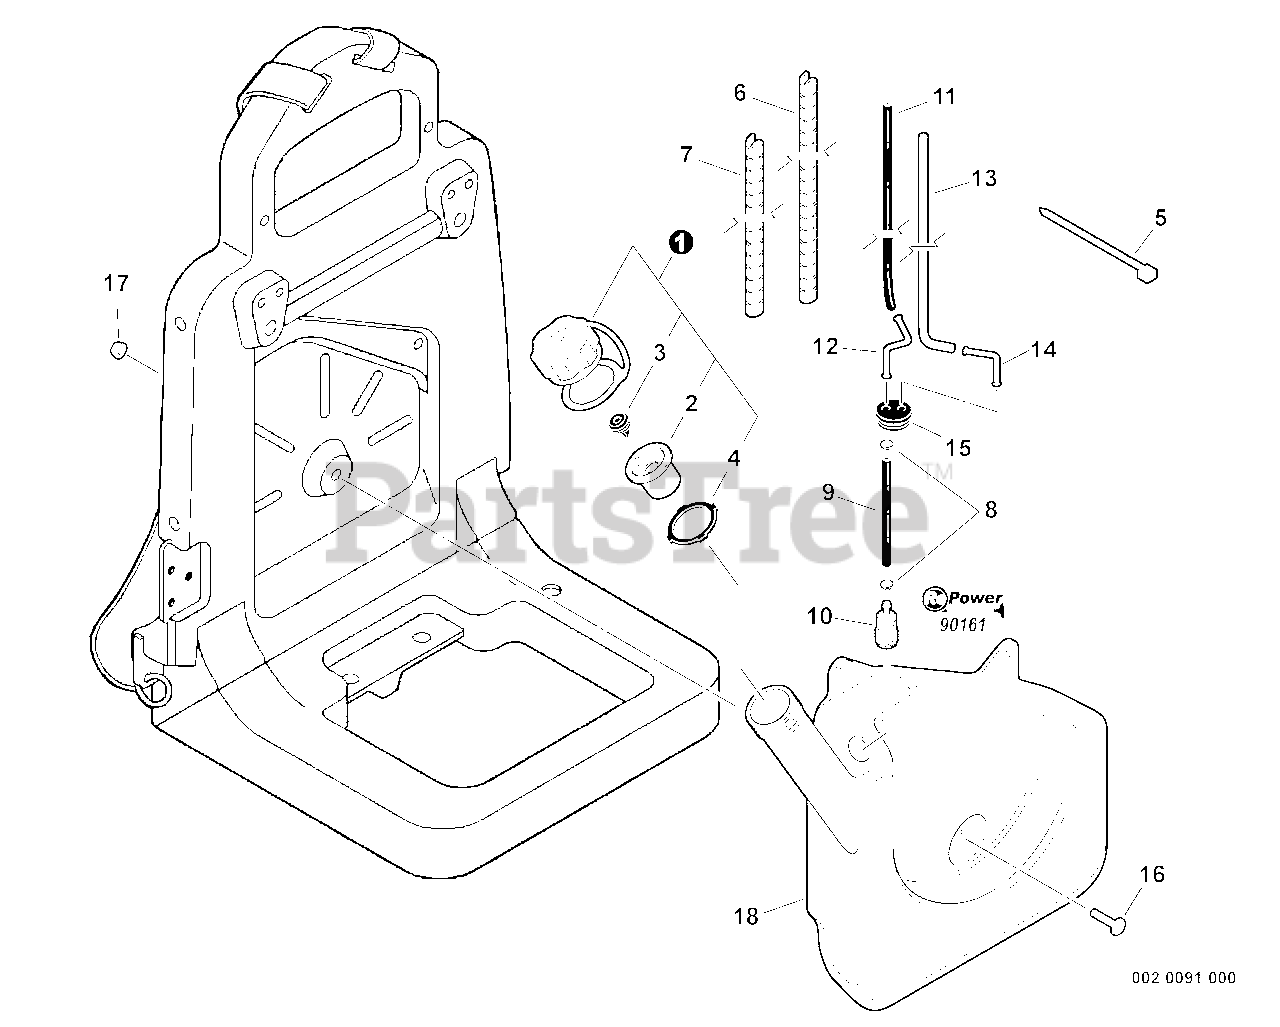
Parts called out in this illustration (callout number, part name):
1	CAP ASSY
2	VENT HOLDER ASSY
4	GASKET, CAP
5	TIE, CABLE - SMALL
6	WRAP, SPIRAL - 130mm
7	WRAP, SPIRAL
8	CLIP - 6.5
9	PIPE - 3X6X280 -- BLACK
10	FILTER, FUEL
11	PIPE - 3X7X520 -- BLACK
12	CONNECTOR, PIPE
13	PIPE - 2X4X480 -- CLEAR
14	CONNECTOR, PIPE
15	GROMMET
16	SCREW - 5X20
17	NUT - 5 -- FLANGE
18	TANK, FUEL
19	RePower TUNE-UP KIT
